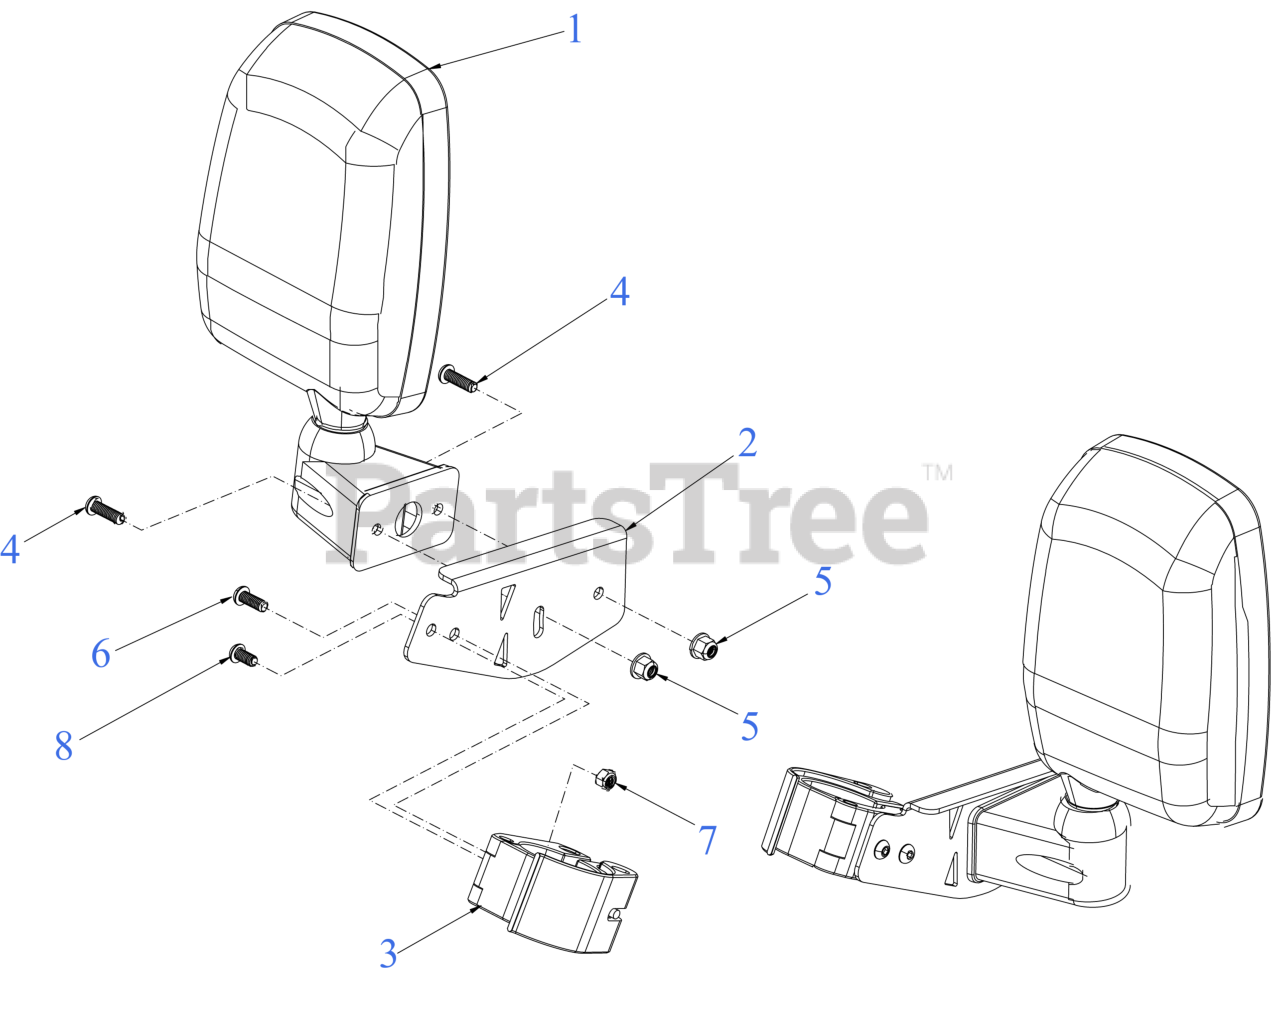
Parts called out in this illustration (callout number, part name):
1	MIRROR
2	MOUNT PLATE L & R
4	BUTTON HEAD SCREW M6x20
5	FLANGE NUT M6
6	BUTTON HEAD SCREW M6x16
7	NYLOCK NUT M6
8	BUTTON HEAD SCREW M6x12
